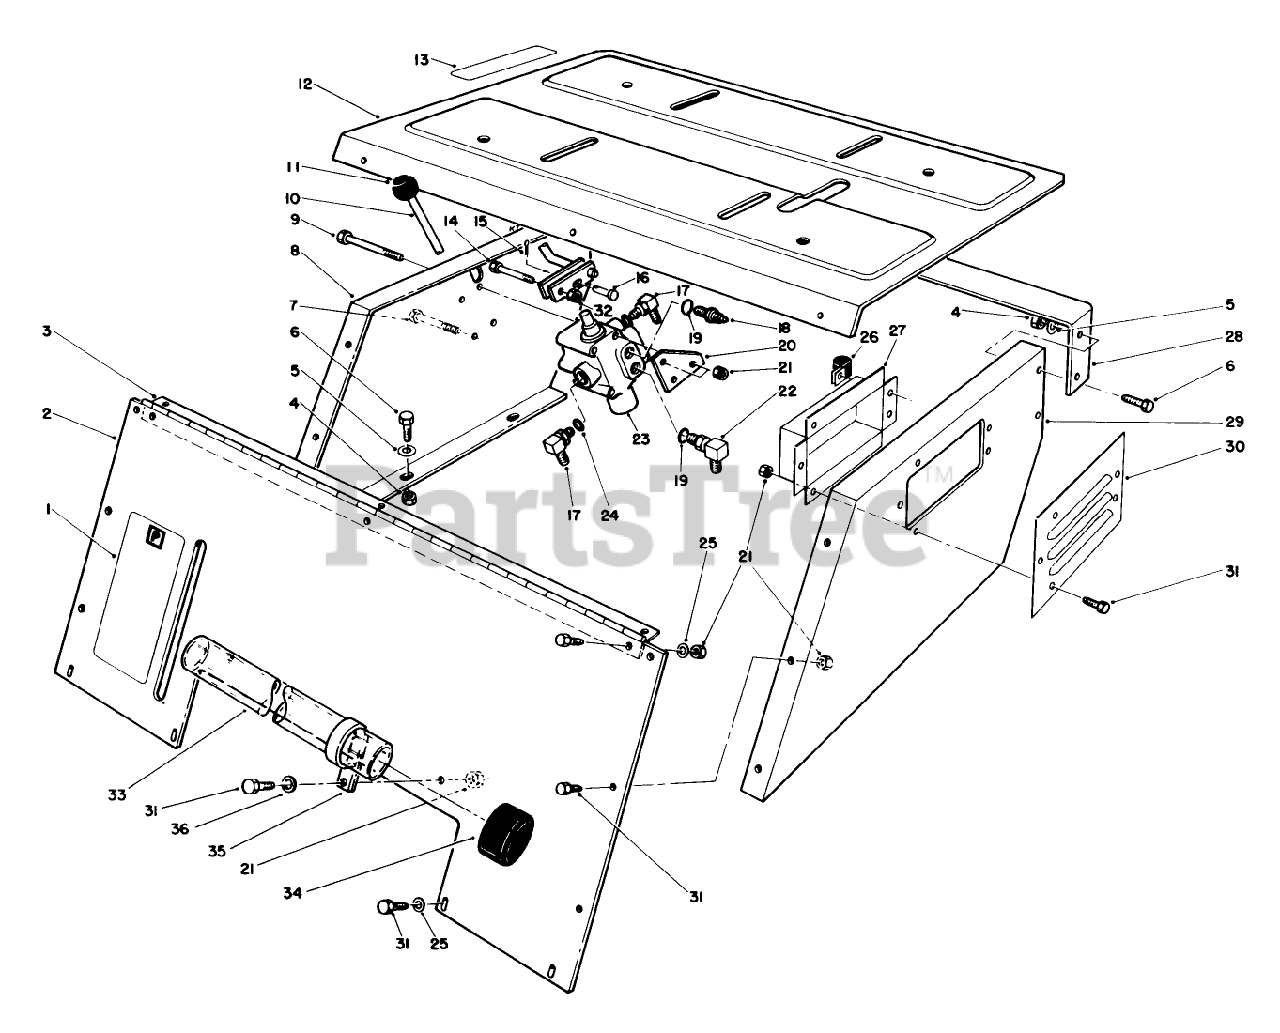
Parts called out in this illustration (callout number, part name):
1	PARK BRAKE DECAL
2	Support-Seat, Front
3	Hinge-Seat
4	NUT-LOCK, NI
5	WASHER-PLAIN
6	SCREW-HH
7	SCREW-HH
8	Support-Seat RH.
9	SCREW-HH
10	VALVE LEVER WA
12	SEAT PLATE R
13	LIFT CONTROL DECAL
14	SCREW-HH
15	PIN-COTTER
16	PIN-CLEVIS
17	FITTING-HYD, 90 DEG
18	FITTING-STRAIGHT
19	O-RING
20	VALVE LEVER BRKT
21	NUT-LOCK, NI
22	FITTING-ELBOW, 90
23	VALVE ASM
24	O-RING
25	WASHER-FLAT
26	CLAMP
27	AIR CHAMBER WA B
28	Support-Hood
29	LH SEAT SUPPORT R
30	AIR CHAMBER COVER R
31	SCREW-HH
32	NUT-HEX
34	CAP-END
35	CLAMP-R
36	WASHER-FLAT
